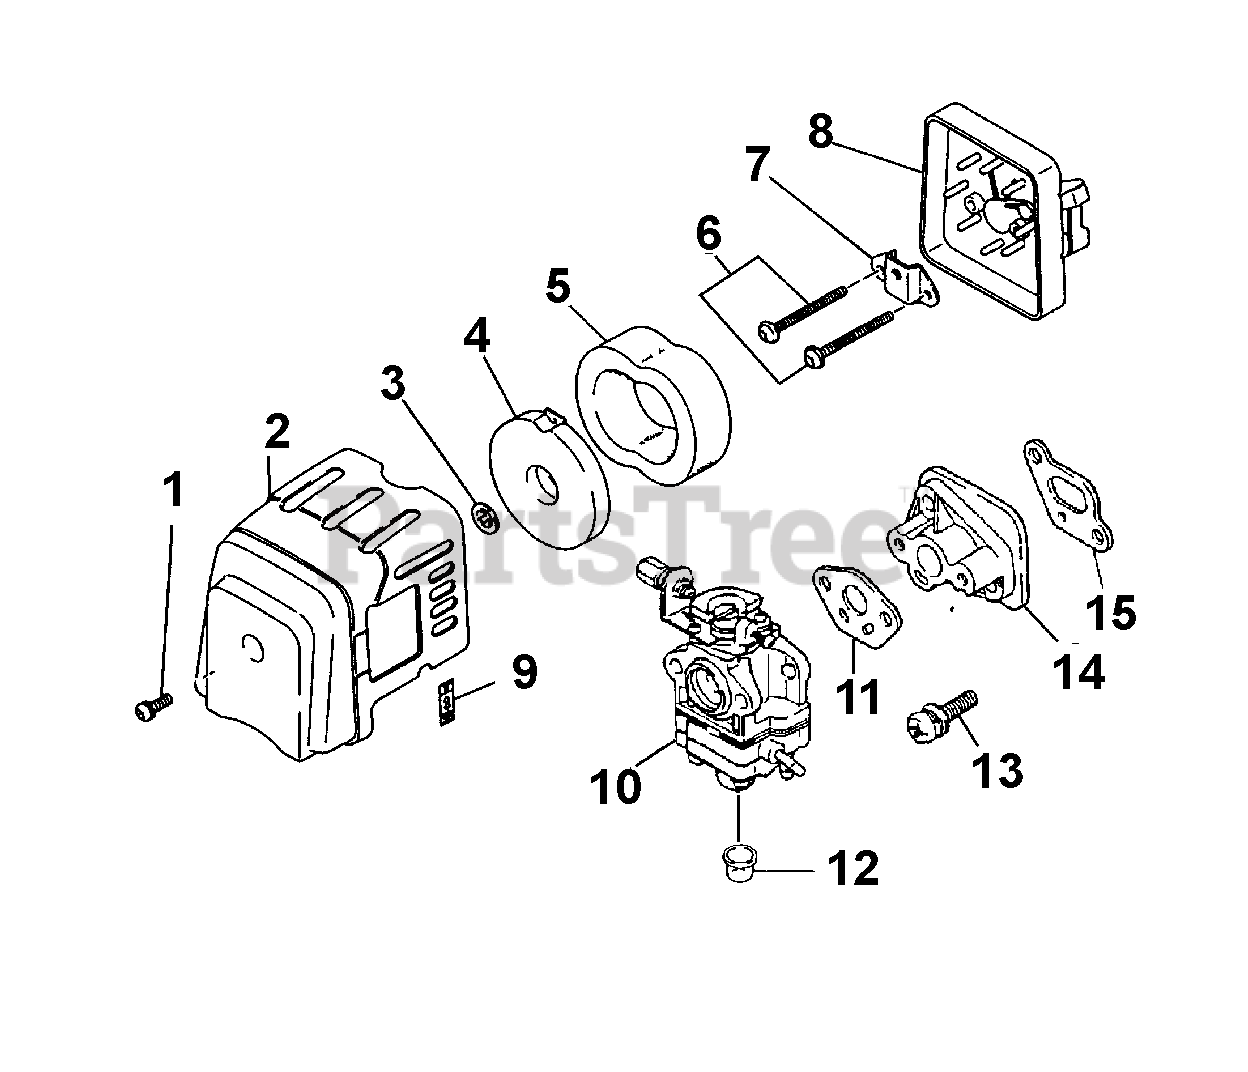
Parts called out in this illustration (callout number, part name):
1	Screw & Washer
2	Cover, Cleaner
3	Pal Nut
6	Screw & Washer
8	Base, Cleaner
9	Label, Choke
10	Carburetor
11	Gasket, Carburetor
12	Primer Bulb
13	Screw & Washer
14	Insulator
15	Gasket, Insulator
